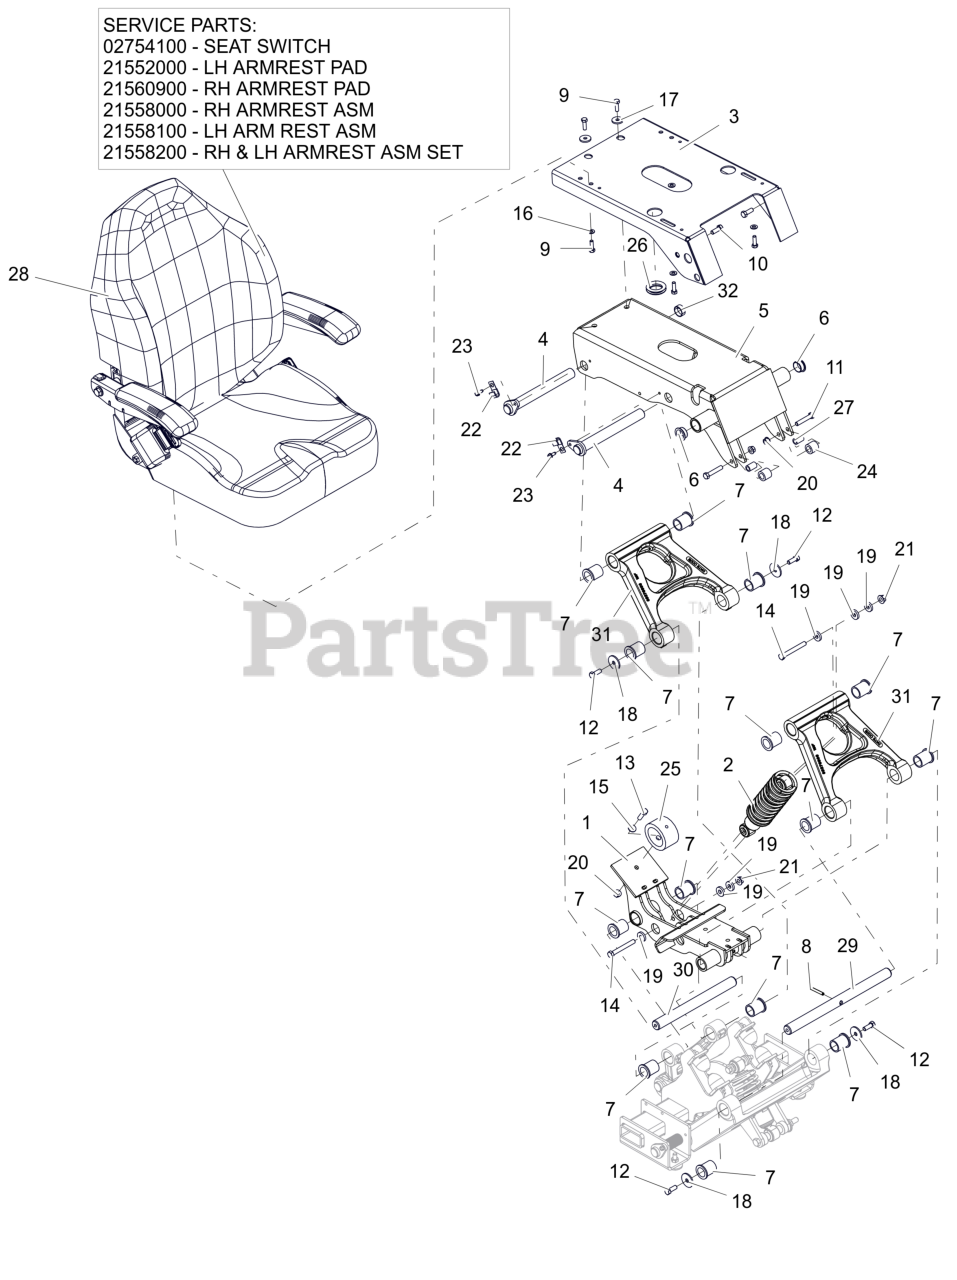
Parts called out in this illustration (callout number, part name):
1	MACHINED, SUSPENSION MID LINK (BLACK)
2	SHOCK, UPPER - TENNECO
3	WLDMT- SEAT MOUNT - RED
4	WLDMT, UPPER PIVOT SHAFT (RED)
5	WLDMT, SEAT MOUNTING SUPPORT (RED) W/ SAFETY DECALS
6	BSHG-FLG 1.0X1.125X.50X1.375 R
7	BEARING, SINTERED BRONZE FLANGE
8	PIN-ROLL .250X1.75
9	BLT,HEX .31-18X1.00 G5 ZCC
10	BLT,HEX .38-16X1.00 G5 ZCC
11	BLT,HEX .38-16X2.00 G5 ZCC
12	BLT, HEX .38-16X1.00 G8ZCCEP30
13	BLT, HEX .38-16X1.25 G5 ZCC
14	BLT,HEX M10-1.5X80 G10.9 ZCC
15	WSHR,FLT .406X.812X.065 ZCC
16	WSHR,FLT .344X.688X.065 ZCC
17	WSHR, FLT .340X1.125X.135 ZCC
18	WSHR, FLT .380X1.50X.125 ZCC
19	WSHR, FLT .406X1.00X.188 ZCC
20	NUT-LK-CTR-FLG .375-16 GF ZCC
21	NUT, FLG-CTR LK M10-1.50 ZCC
23	SCR,TAP .25-20X.625 HWH ZCC
24	BUMPER,RUBBER .62X1.0X.88 LG
25	BUMPER, RADIAL (GBR)
26	GROMMET 1.25ID X 1.5OD
27	BUSH.,S.391X.622X.950 ST
28	SEAT, PT600
28	SWITCH- SNAP MTG N.O.
28	PAD, ARMREST LH
28	PAD, ARMREST RH OR LH (HARD)
28	ARMREST, RH ASSEMBLY
28	ARMREST, LH ASSEMBLY
28	SET, RH & LH ARMREST ASSEMBLY
29	SHAFT, PIVOT
30	SHAFT, PIVOT
31	MACHINED, UPPER LINK
32	CAP, 1.000 ID X .375 DEEP
